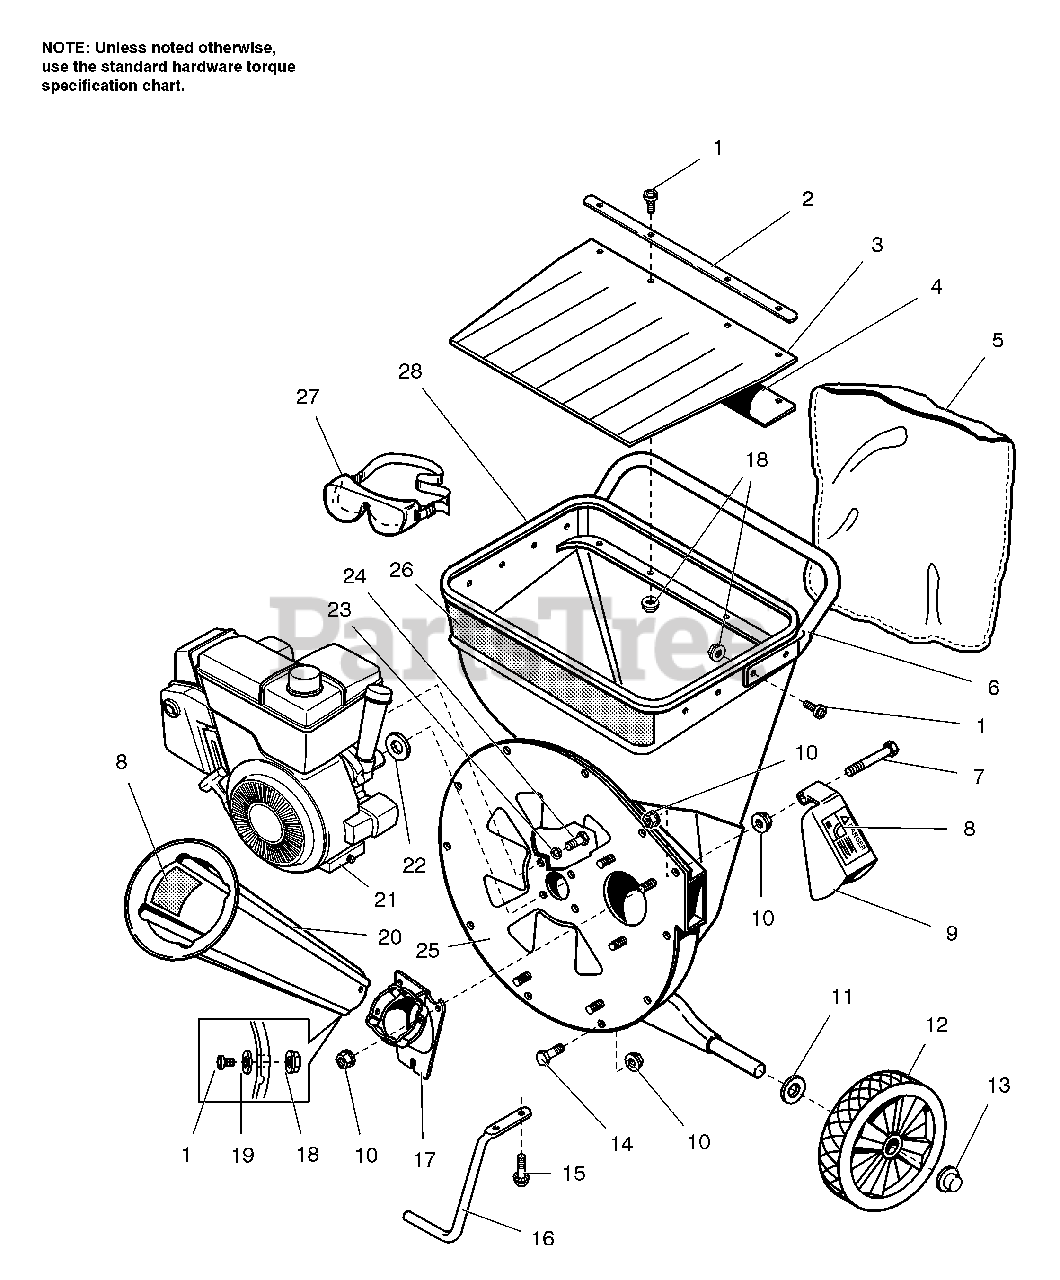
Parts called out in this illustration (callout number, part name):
1	SCREW, Button Hd., Hex socket, 1/4-20 x 3/4
2	RETAINER STRIP, Hopper Guard
3	GUARD, Hopper
4	SUPPORT, Hopper Guard
5	BAG, Collection, 24" x 36"
6	HANDLE, Hopper
7	CAPSCREW, Hex Hd. 5/16-18 x 3-1/4, Grade 5
8	DECAL, Danger
9	DEFLECTOR, Discharge
10	NUT, Hex Whiz-lock, 5/16-18
11	WASHER, Plain, 17/32 x 1-1/4 x 5/64
12	WHEEL & TIRE, 1.75 x 12"
13	PUSH NUT, 1/2" dia.
14	CAPSCREW, Hex Hd., 5/16-18 x 5/8
15	SCREW, Taptite, 3/8-16 x 1-1/4
17	CHIPPER CONE CASTING, 3"
18	FLANGE NUT, 2-way lock, 1/4-20
19	WASHER, Plain
20	CONE, Chipper, 3" Yellow
20	CONE, Chipper, 3" Orange
21	ENGINE
23	LOCKWASHER, Spring, 5/16
24	CAPSCREW, Hex, 5/16-24 x 3/4
25	ENGINE PLATE ASSY.
26	DECAL, 6/14E Simplicity
26	DECAL, 6/14E Baker
28	HOPPER-SHREDDER, Yellow
28	HOPPER-SHREDDER, Orange
